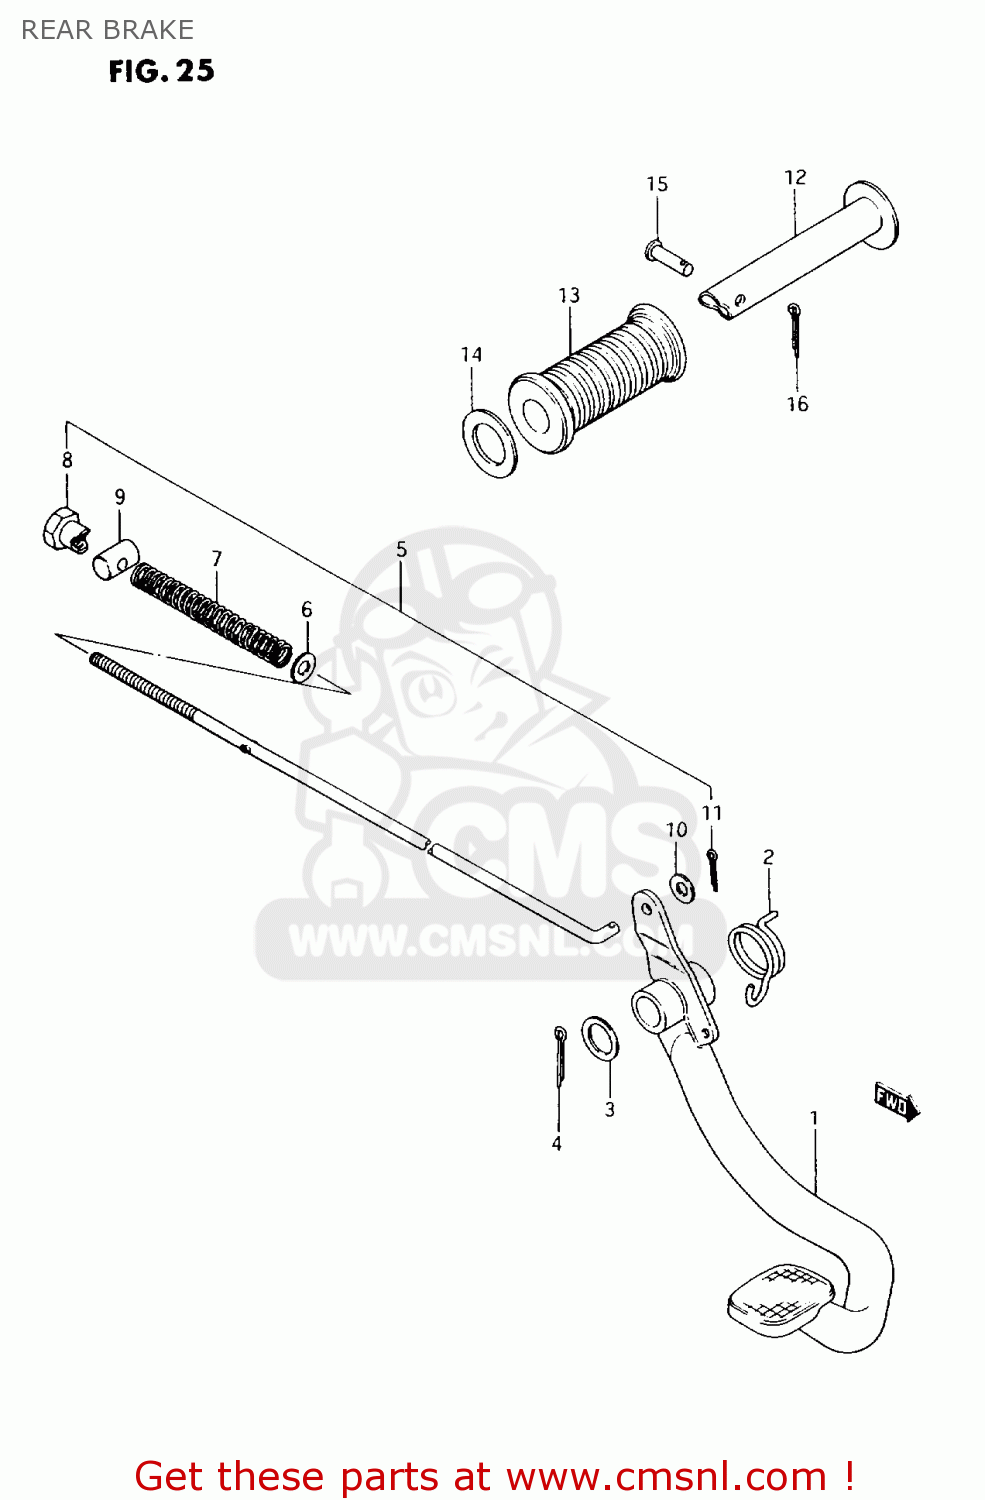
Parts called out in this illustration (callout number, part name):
1	PEDAL,BRAKE
2	SPRING
3	WASHER(15.5X26X2.3)
4	COTTER PIN
5	ROD ASSY,RR BRAKE
6	WASHER
7	SPRING
8	NUT
9	PIN(11X18)
10	WASHER
11	PIN 20X20
12	BAR,FOOTREST RUBBER
13	RUBBER,PILLION FOOTREST
14	WASHER (19.5X32X2)
15	PIN
16	PIN
